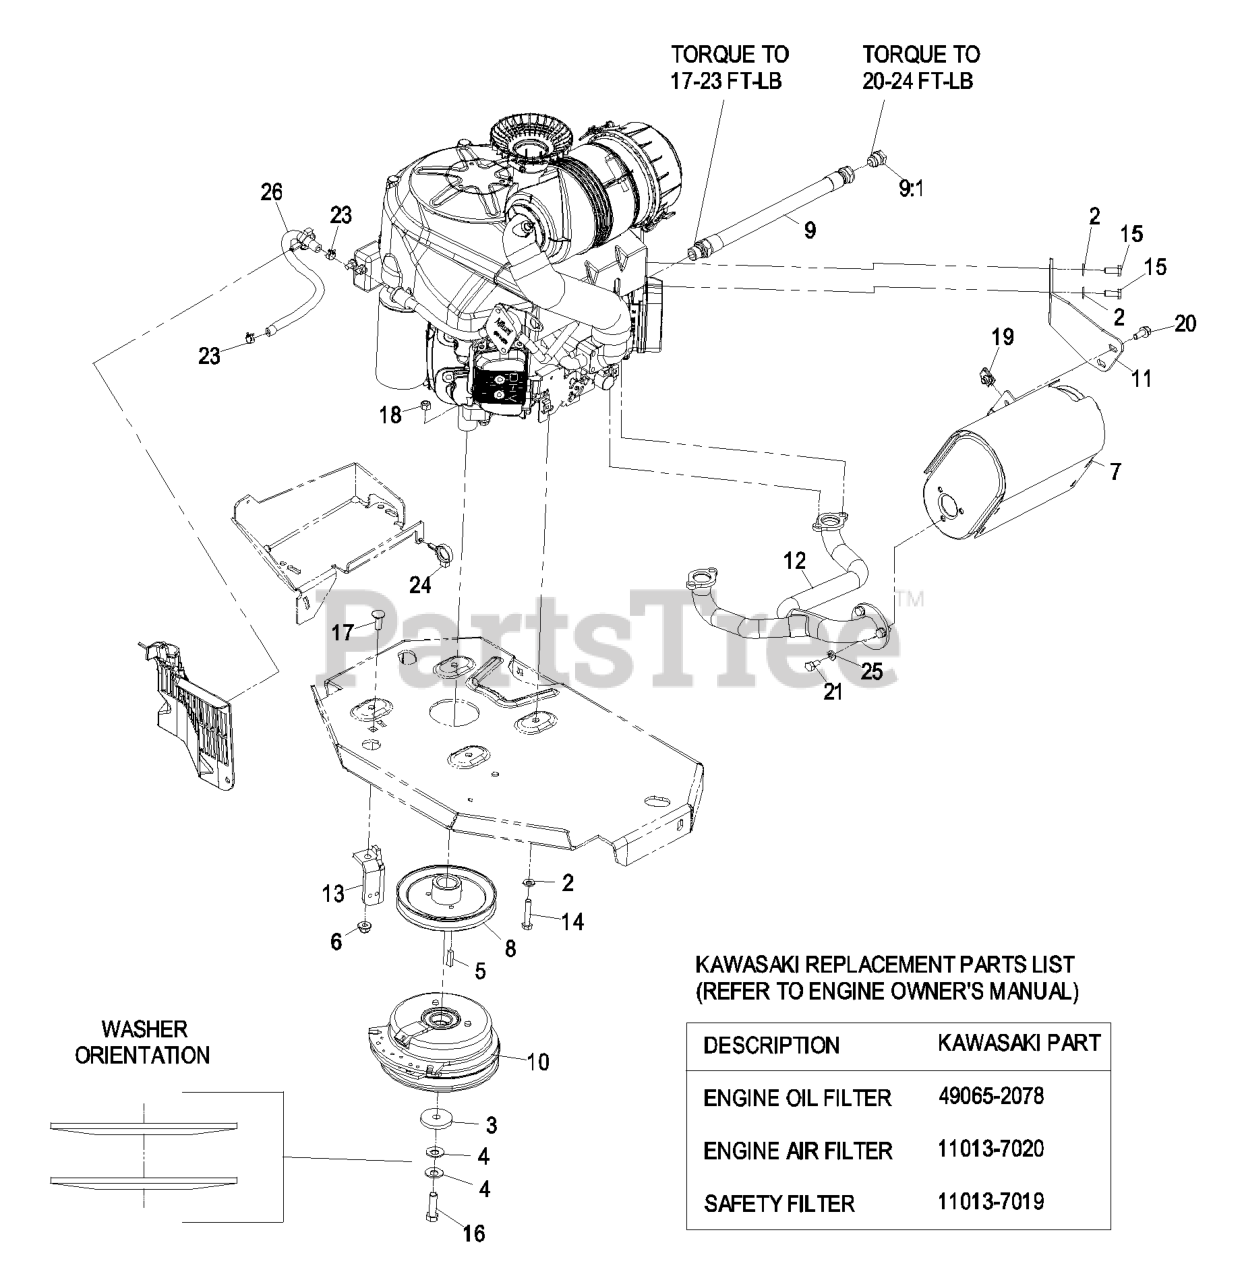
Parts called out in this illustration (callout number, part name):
2	WASHER-SPRING
3	WASHER-CLUTCH
4	WASHER-SPRING
6	NUT-HF, NI
7	MUFFLER-ENGINE
8	SHEAVE
12	MANIFOLD-EXHAUST
13	ANCHOR-CLUTCH
14	SCREW-HH
15	SCREW-HH
16	SCREW-HH 7/16-20 X 1 1/2 W/LOCTITE
17	SCREW-CARR
18	NUT-LOCK, NI
20	SCREW-HHF
21	SCREW-HH
23	CLAMP-HOSE
24	CLAMP-HOSE
25	WASHER-LOCK
26	HOSE-FUEL
